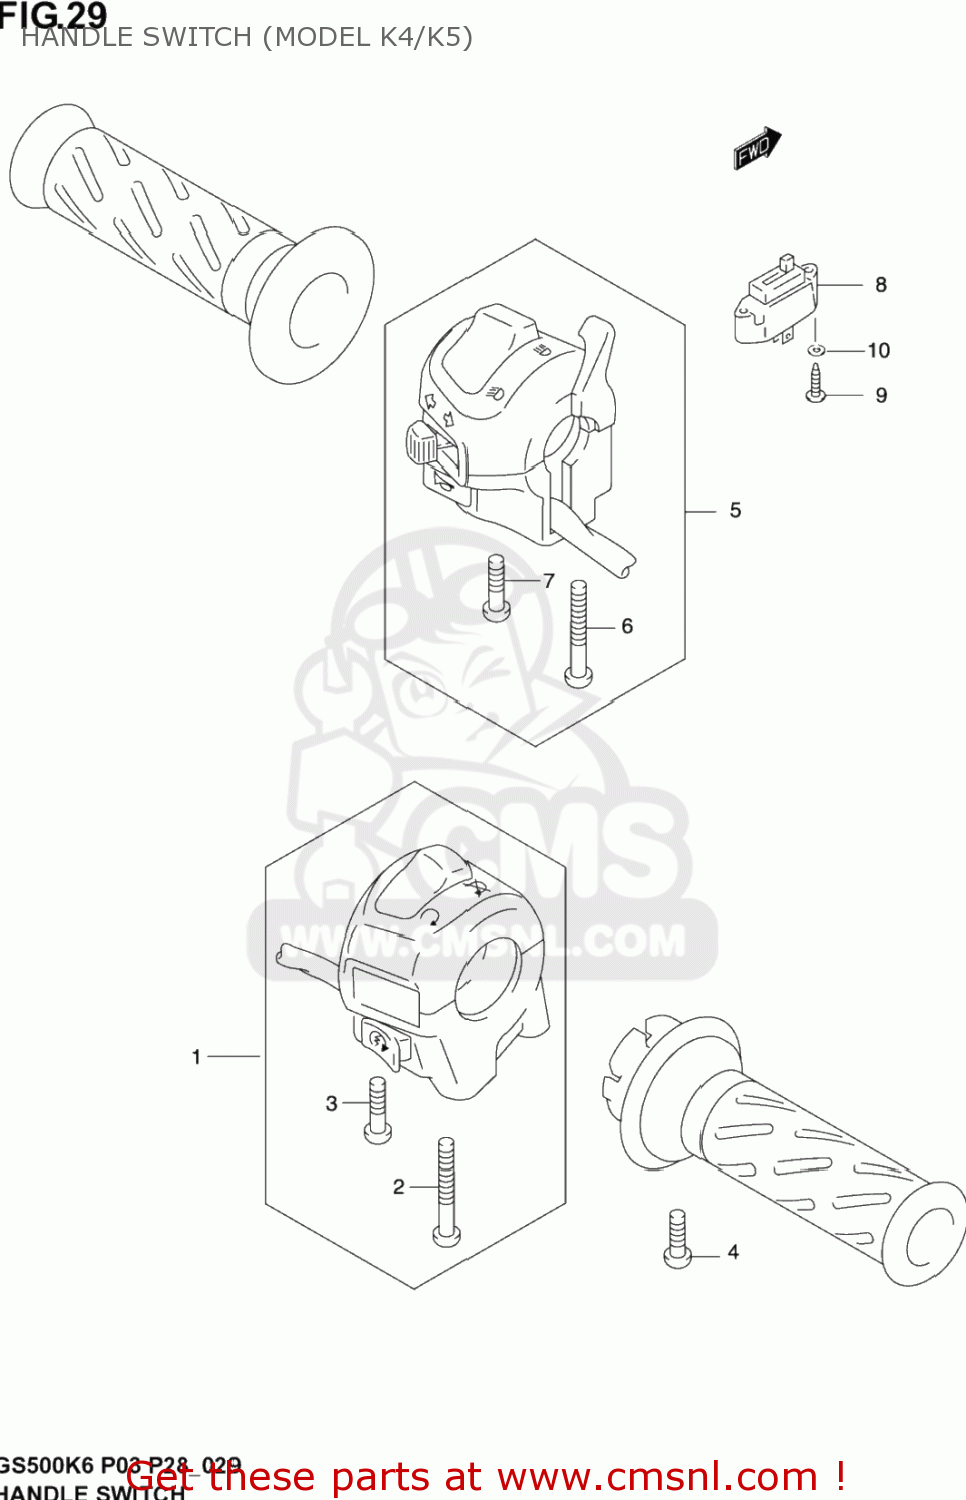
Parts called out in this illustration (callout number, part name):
1	SWITCH ASSY,HA
2	SCREW
3	SCREW
4	SCREW
5	SWITCH ASSY, HANDLE LH
6	SCREW
7	SCREW
8	SWITCH ASSY,CLUTCH
9	SCREW(3X14)
10	WASHER
